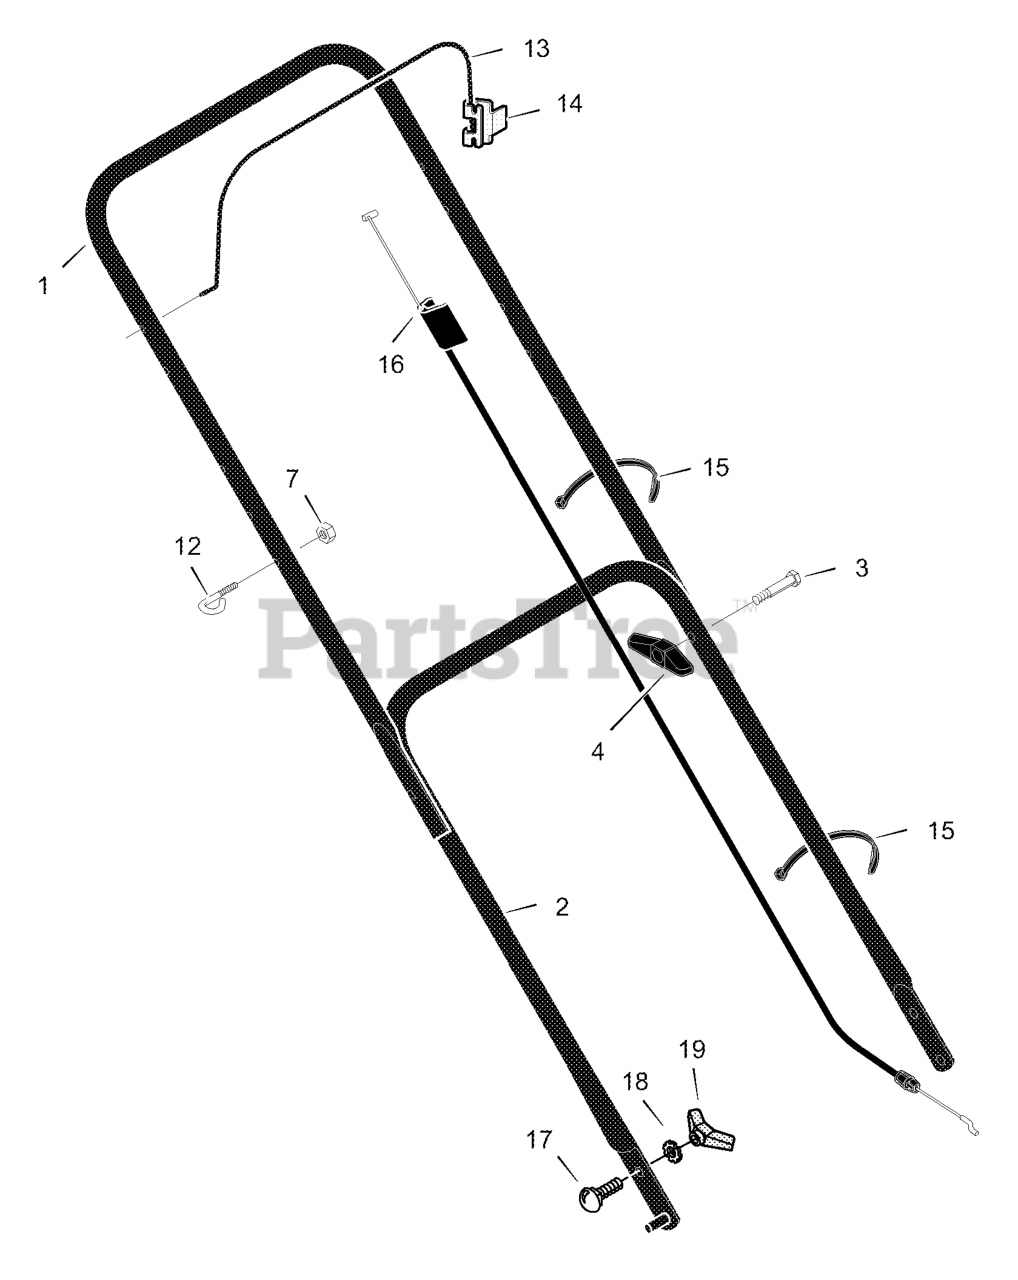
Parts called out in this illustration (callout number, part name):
1	Handle, Upper (Black)
2	Handle, Lower (Black)
4	Knob, Plastic
7	Locknut
12	Guide, Rope
13	Engine Stop Lever
14	Bracket, Stop Lever
15	Fastener, Cable
16	Engine Stop Cable
17	Bolt, Carriage
18	Washer
19	Knob, Plastic
